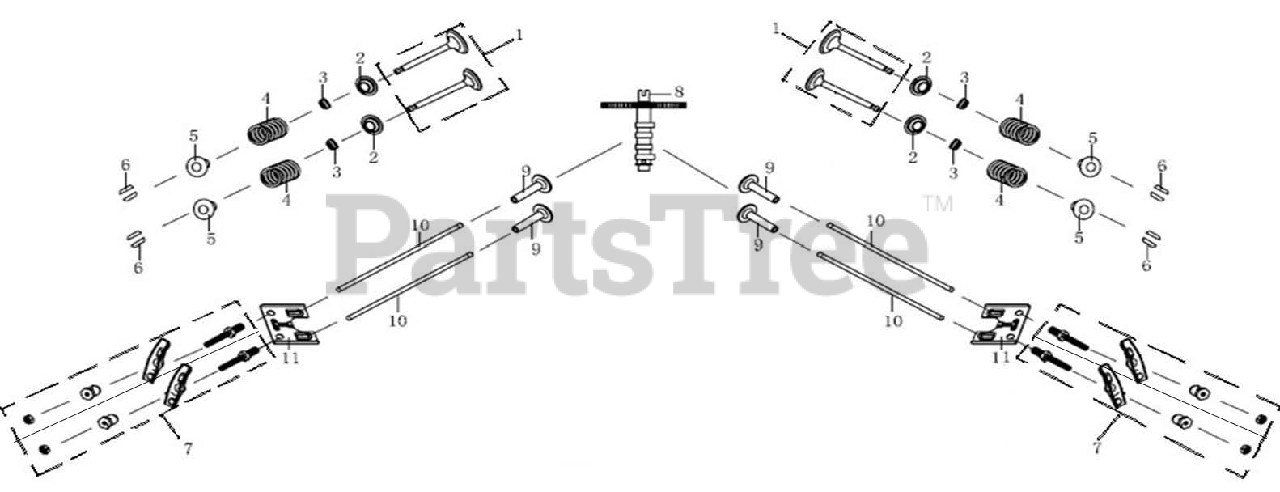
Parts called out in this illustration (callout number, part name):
1	VALVE KIT
2	SEAT, VALVE SPRING
3	VALVE OIL SEAL
4	INNER SPRING OF VALVE
5	RETAINER, VALVE SPRING
6	VALVE LOCKER
7	VALVE ROCKER COMBINATION
8	CAMSHAFT ASSY
9	LIFTER, VALVE
10	PUSH ROD
11	PLATE, PUSH ROD GUIDE
